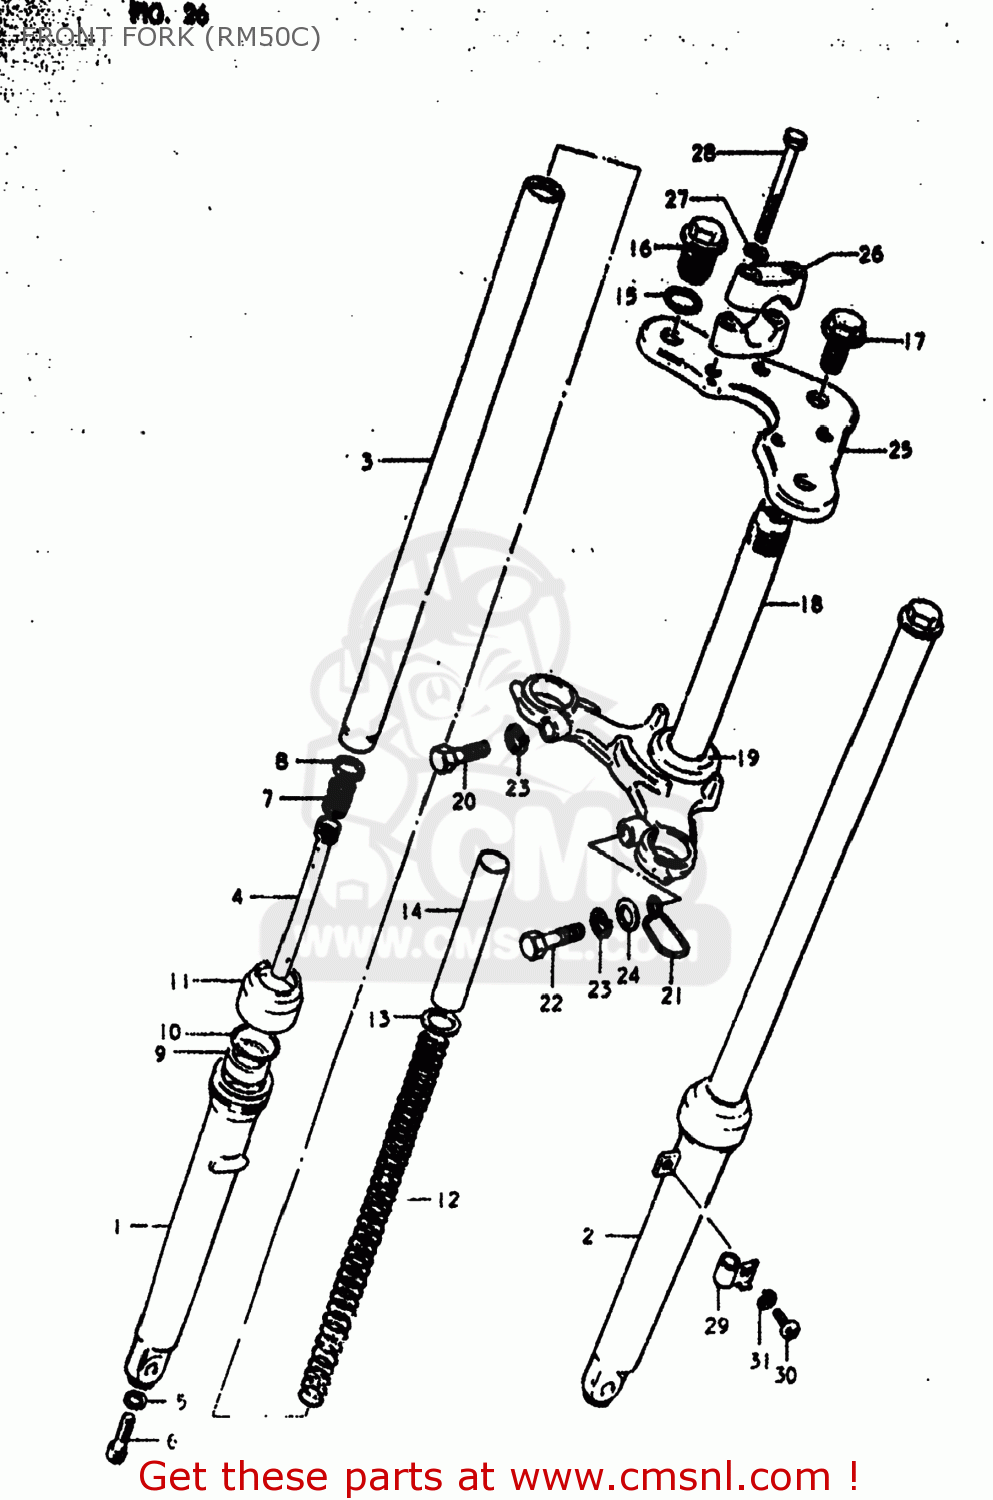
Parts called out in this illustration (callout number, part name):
0	DAMPER SET
1	TUBE,OUTER,RIGHT
2	TUBE,OUTER,LEFT
3	TUBE,FORK,INNER
4	CYLINDER,FRONT FORK
5	GASKET (NAS)
6	BOLT
7	SPRING,REBOUND
8	RING,PISTON
9	OIL SEAL,FRONT FORK
10	CIRCLIP,FORK OIL SEAL
11	DUST SEAL
12	SPRING
13	JOINT,SPRING
14	SPACER,SPRING
15	O-RING,FORK INNER TUBE
16	CAP
17	BOLT
18	STEM,STEERING
19	RACE,STEERING OUTER LWR
20	BOLT 10X30
21	CLAMP,METER CABLE
22	BOLT,M10X1.25X
23	LOCK WASHER
24	WASHER
25	HEAD,STEERING STEM
26	HOLDER,HANDLE UPR
27	LOCK WASHER
28	BOLT 8X55
29	CLIP,CABLE
30	SCREW
31	LOCK WASHER
